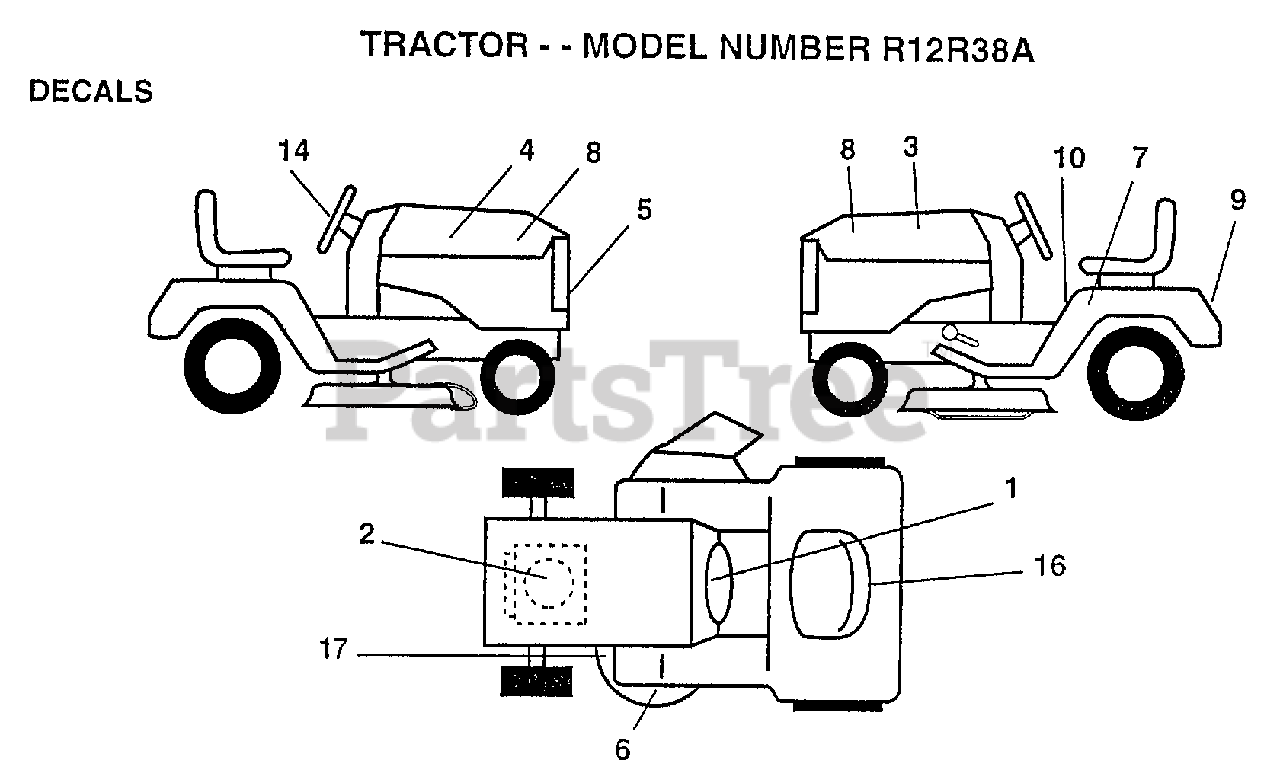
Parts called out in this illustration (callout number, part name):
1	DECAL.INST.OPER
2	DECAL, HP ENGINE
3	DECAL HD RLY LH
4	DECAL HD RLY RH
5	GRILL DECAL
7	IND HGT DECK DECA
8	DECAL.INSERT.HOOD
9	FENDER DECAL
10	DECAL
14	"DECAL,STR WHL"
16	DECAL.BTRY.DANGER
17	DECAL
